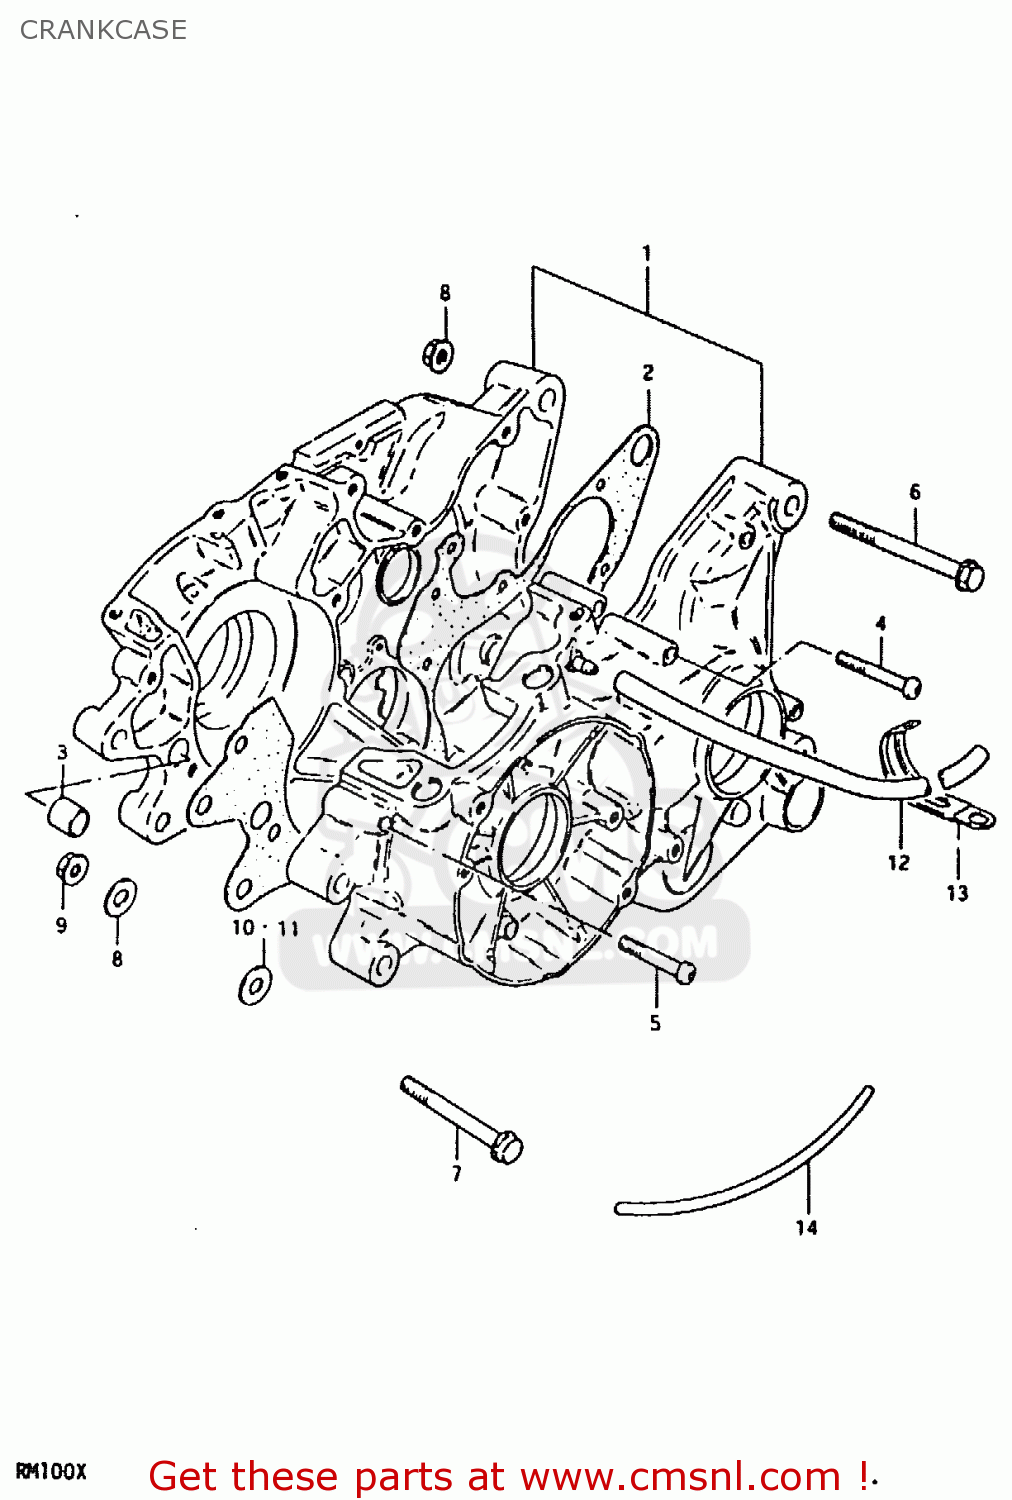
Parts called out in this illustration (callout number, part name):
1	CRANKCASE SET
2	GASKET,CRANKCASE (MCA)
3	PIN
4	SCREW
5	SCREW (6X45)
6	BOLT
7	BOLT(8X67)
8	WASHER
9	NUT
10	WASHER
11	WASHER
12	HOSE
13	CLAMP
14	HOSE
